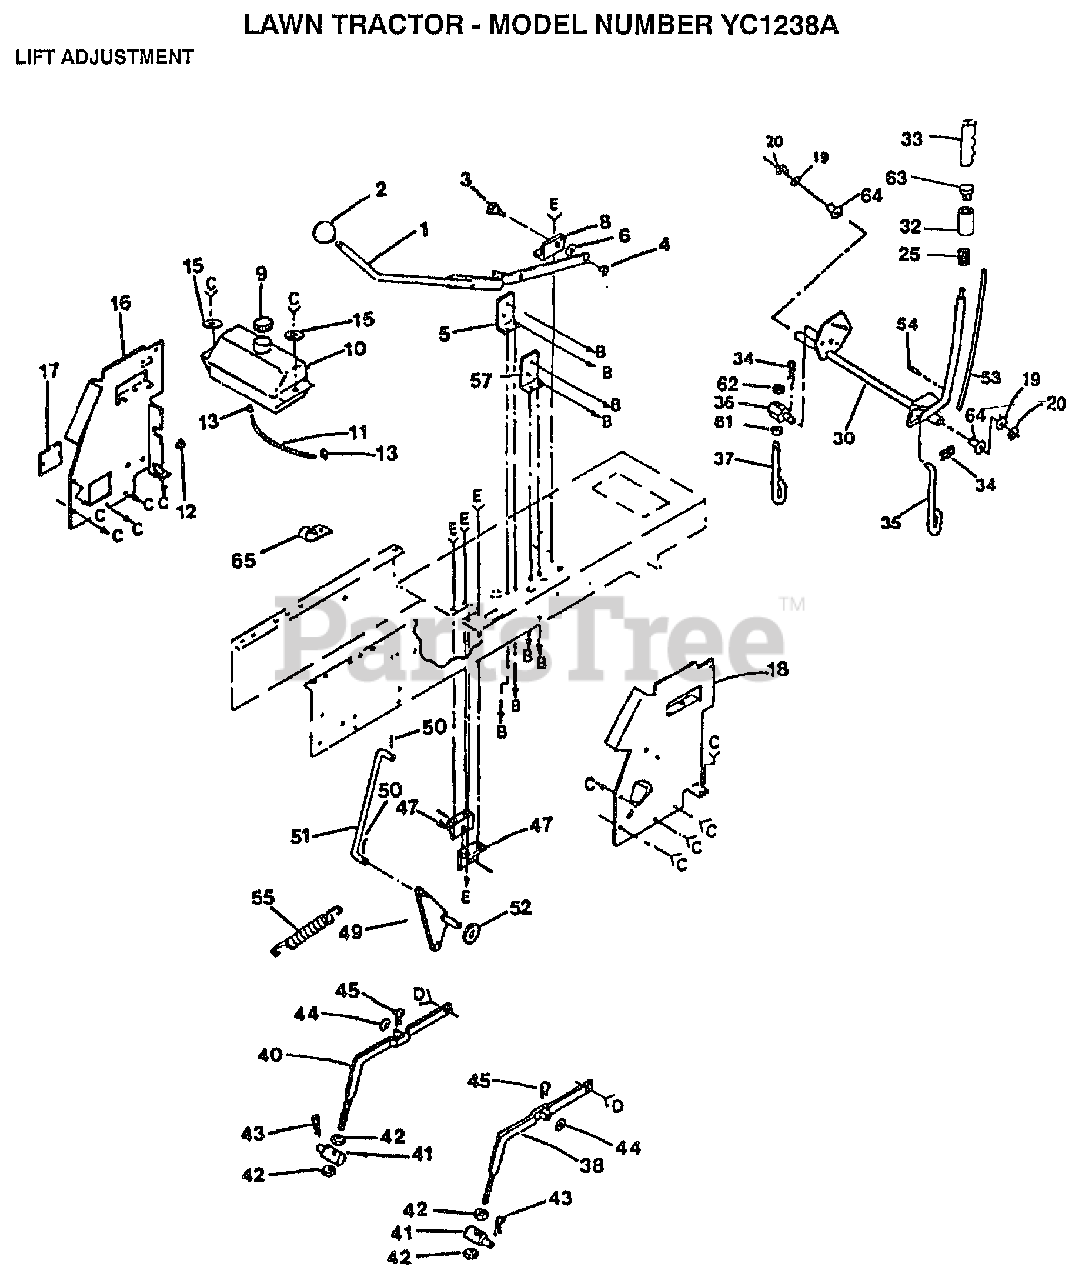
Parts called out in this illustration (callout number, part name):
3	"BOLT, SHOULDER LT"
5	"BRACKET,SWITCH LT"
7	SCREW
8	"SUP,LVR,CLUTCH LT"
10	TANK.FUEL.LT.
12	SNAP BUSHING T
13	HOSE CLAMP
14	SCREW HEX CRT
15	WASHER
16	PANEL DASH LH
17	COVER ACCESS
19	WASHER
26	WASHER
27	TRUNION LT
28	WASHER
29	KLIP RING
33	GRIP
35	LIFT LINK LT
37	PIVOT PIN T
38	RH SUSP ARM ASM
39	"BOLT, SHOULDER LT"
40	LH SUSP ARM ASM
42	NUT
43	SPRING H
45	SPRING.RETAINER
47	"BRKT,BELLCRAN T"
49	"T, BELLCRANK"
50	COTTER PIN
52	WASHER
54	PIN-GROOVE LT
57	BRACKET LT
58	NUT T
59	WASHER T
60	NUT SPECIAL T
61	NUT
64	NYLON BEARING
65	INSUL CLIP T
70	NUT
